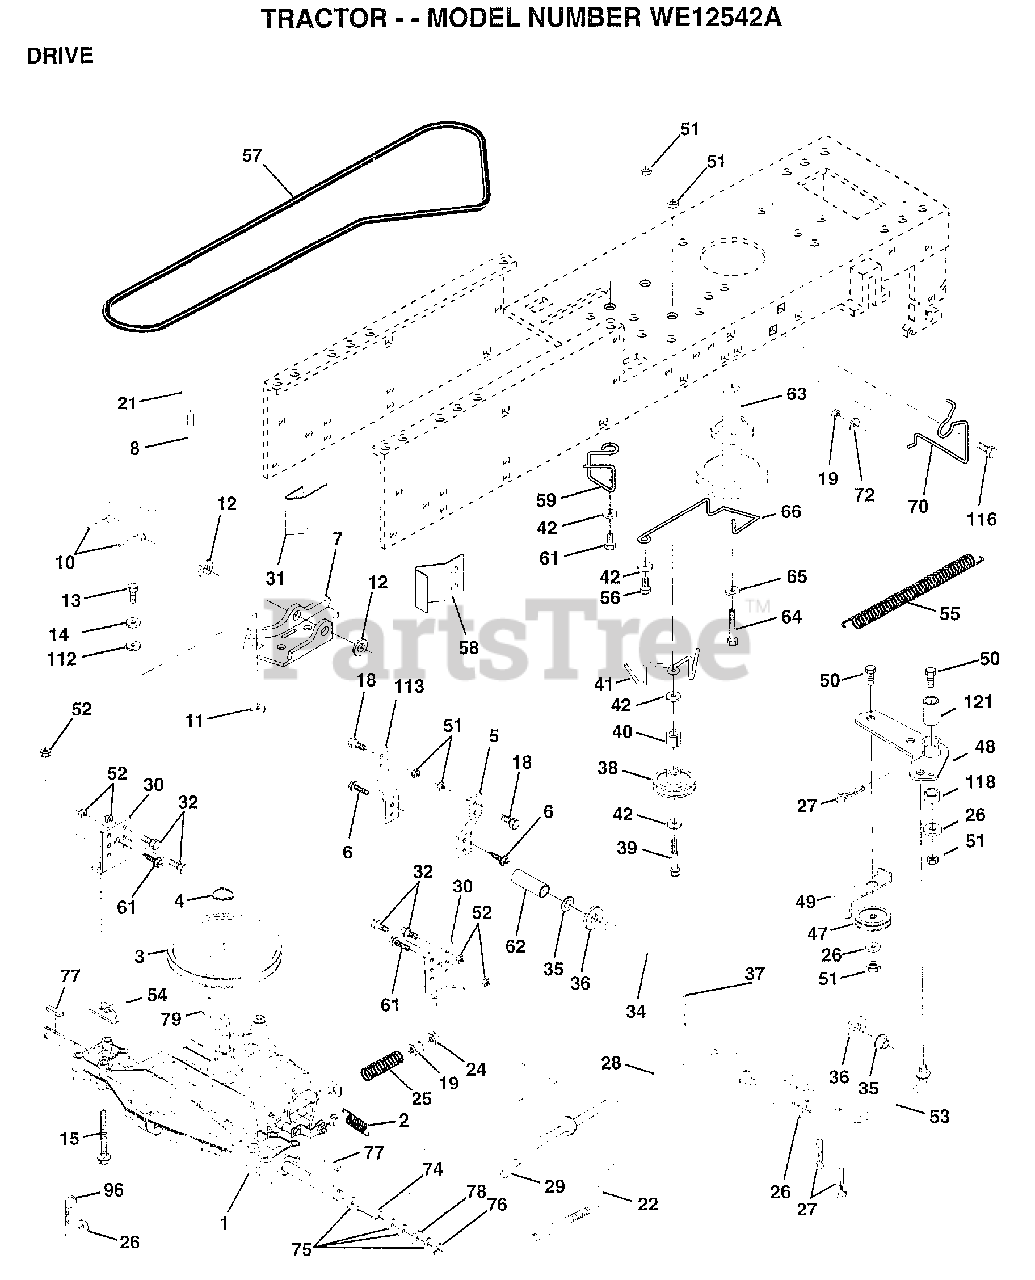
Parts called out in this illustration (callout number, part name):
2	SPRING.BRAKE.RETU
3	PULLEY TRANS
5	STRAP TORQUE
6	SCREW
8	SHIFT ROD
10	PIN COTTER 1/8
11	WASH-SHFT PLT LT
12	WASHER
13	BOLT.1/4-28.W/PAT
14	LOCKWASHER
15	BOLT.HX.FLG.5/16
18	BOLT
19	NUT
21	KNOB T (1/2-HOLE)
22	BRAKE ROD
24	NUT
25	SPRING ROD LT
26	WASHER
27	COTTER PIN
28	ROD.BRAKE.PARK.LT
29	PLUNGER CAP T
30	TRANSAXLE MTG BKT
31	"KEEPER,BELT LH T"
32	BOLT
34	SHAFT ASM-PEDAL F
35	NYLON BEARING
36	WASHER LT
38	PULLEY.IDLER.FLAT
39	BOLT
40	SPACER T
42	WASHER
48	BELLCRANK ASM
49	RETAIN BELT
53	"LINK, CLUTCH T"
54	CLIP T
55	"SPRING, RETURN LT"
58	"KEEPER,BELT RH T"
59	KEEPER BELT CNTSP
61	SCREW
62	PEDAL COVER T
63	PULLEY.ENGINE
64	BOLT
65	LOCKWASHER
66	KEEPER-BELT
70	KEEPER BELT ENG
72	WASHER
74	SPACER AXLE
75	WASHER
76	E-RING LT
77	SQUARE KEY
78	WASHER
96	RETAINER M
112	WASHER LT
113	"STRAP,TORQUE"
116	BOLT RDHD 3/8-16
118	SPACER-BELLCRANK
121	NYLINER-CLUTCHING
